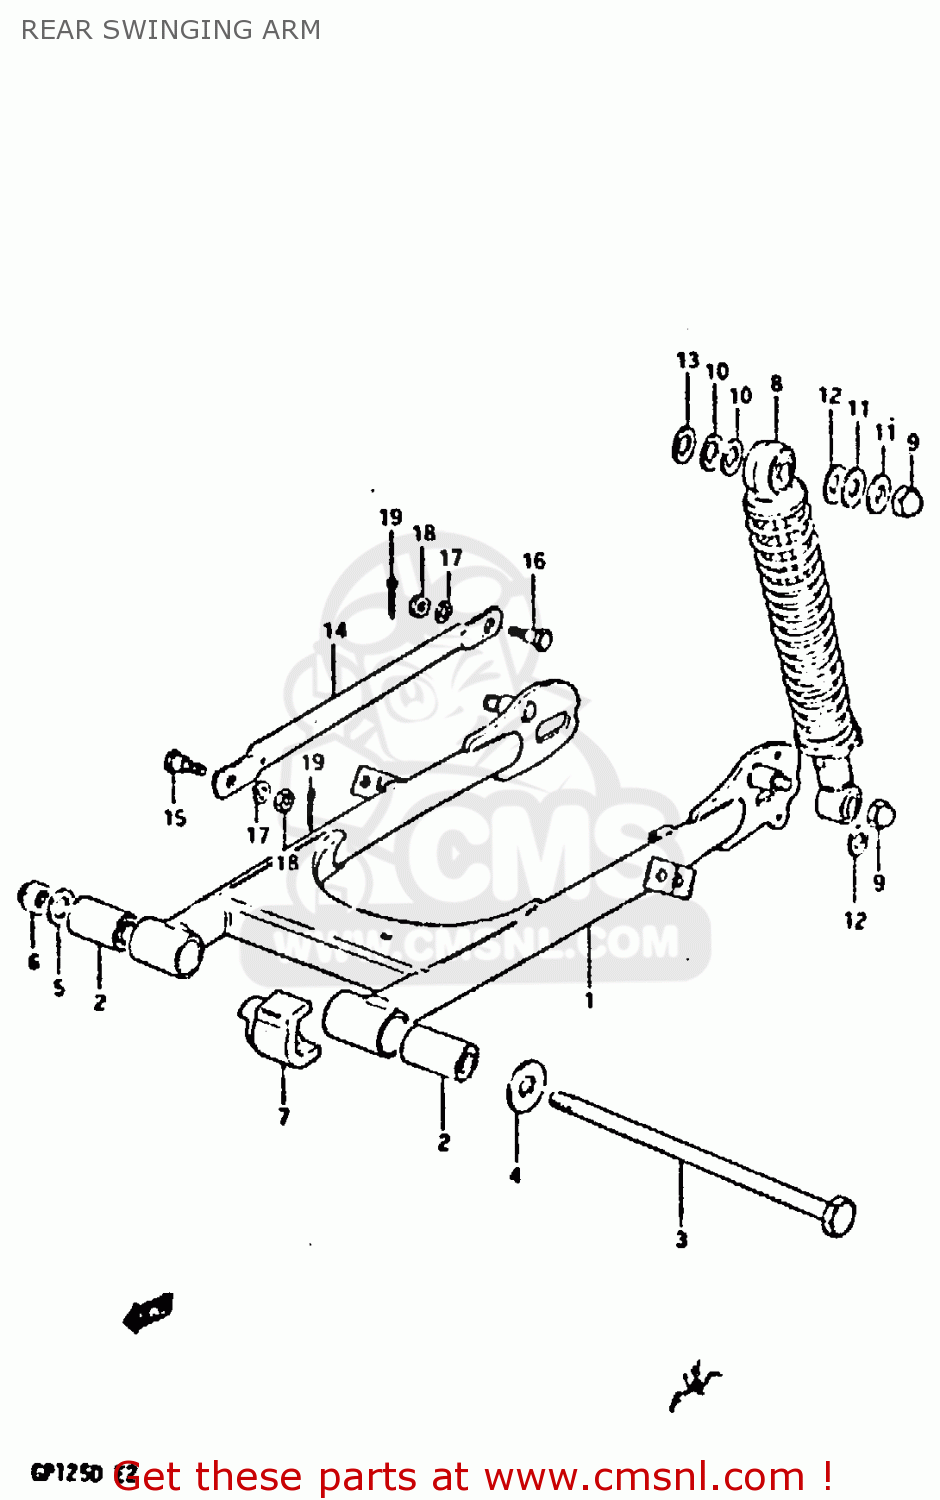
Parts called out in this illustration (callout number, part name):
1	REAR SWINGING ARM SET
2	BUSH(12X24X44)
3	SHAFT,REAR SWING ARM
4	WASHER(12.5X32X2.3)
5	WASHER
6	NUT
7	BUFFER,CHAIN TOUCH DEFENSE
8	ABSORBER ASSY, REAR SHOCK
9	NUT, LOWER LH
10	WASHER
11	WASHER
12	WASHER(10.5X24X3.2)
13	WASHER (12.5X24X3.2)
14	LINK,REAR TORQUE
15	BOLT(8X22.5)
16	BOLT(8X26.5)
17	LOCK WASHER
18	NUT
19	PIN 20X20
